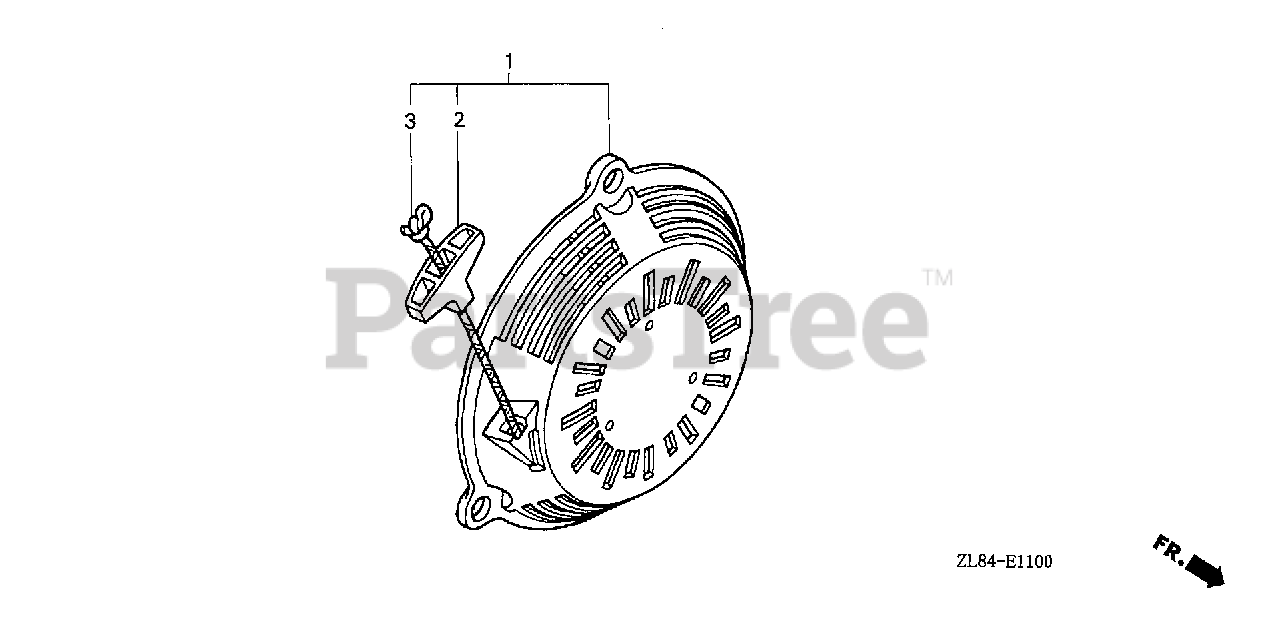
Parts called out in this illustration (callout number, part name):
1	STARTER ASSY., RECOIL *NH1* (BLACK)
2	KNOB, RECOIL STARTER
3	ROPE, RECOIL STARTER
